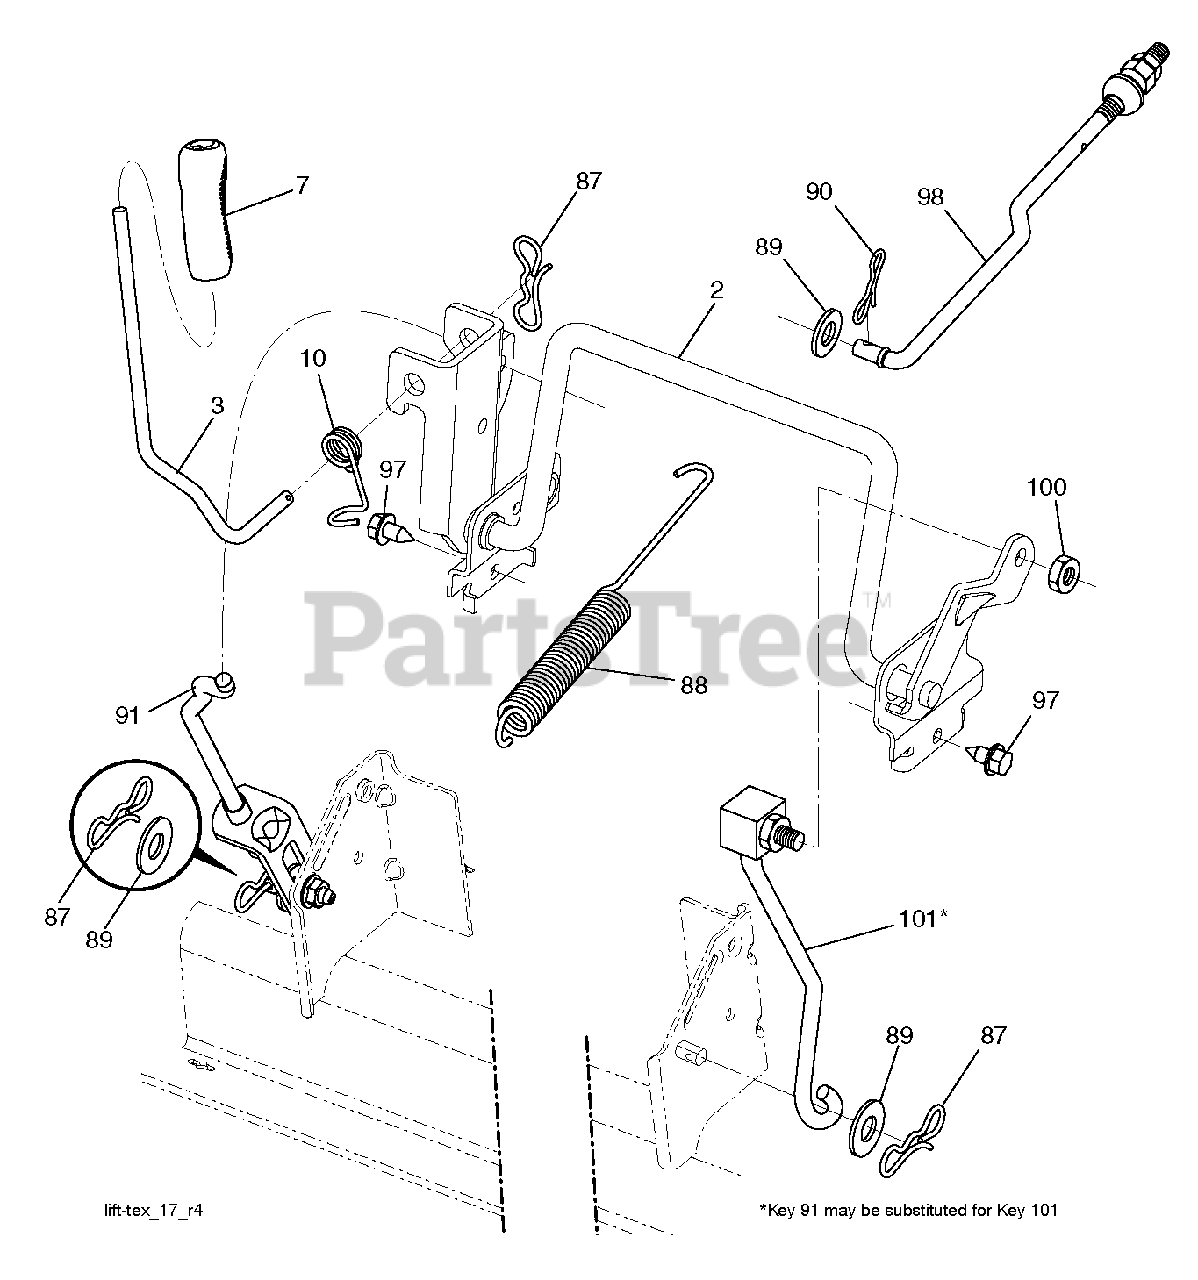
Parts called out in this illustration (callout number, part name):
2	SHAFT LIFT DECK WELD
3	LEVER.LIFT.HANDLE.LT
7	GRIP.HANDLE.LIFT.PVC.BLACK
10	SPRING.TORSION.LIFT.HANDLE
87	PIN.COTTER.7/16.BOW TI.
88	SPRING SPRING LIFT ASSIST 97
89	WASHER.CLEAR.ZINC
90	PIN.COTTER.5/16.BOW TI
91	LINK.ASM.LIFT.REAR
98	LINK.ASM.SUSP.FRONT.MW
100	LOCKNUT
101	LINK.ASM.LIFT.FIXE.38/42/46"
